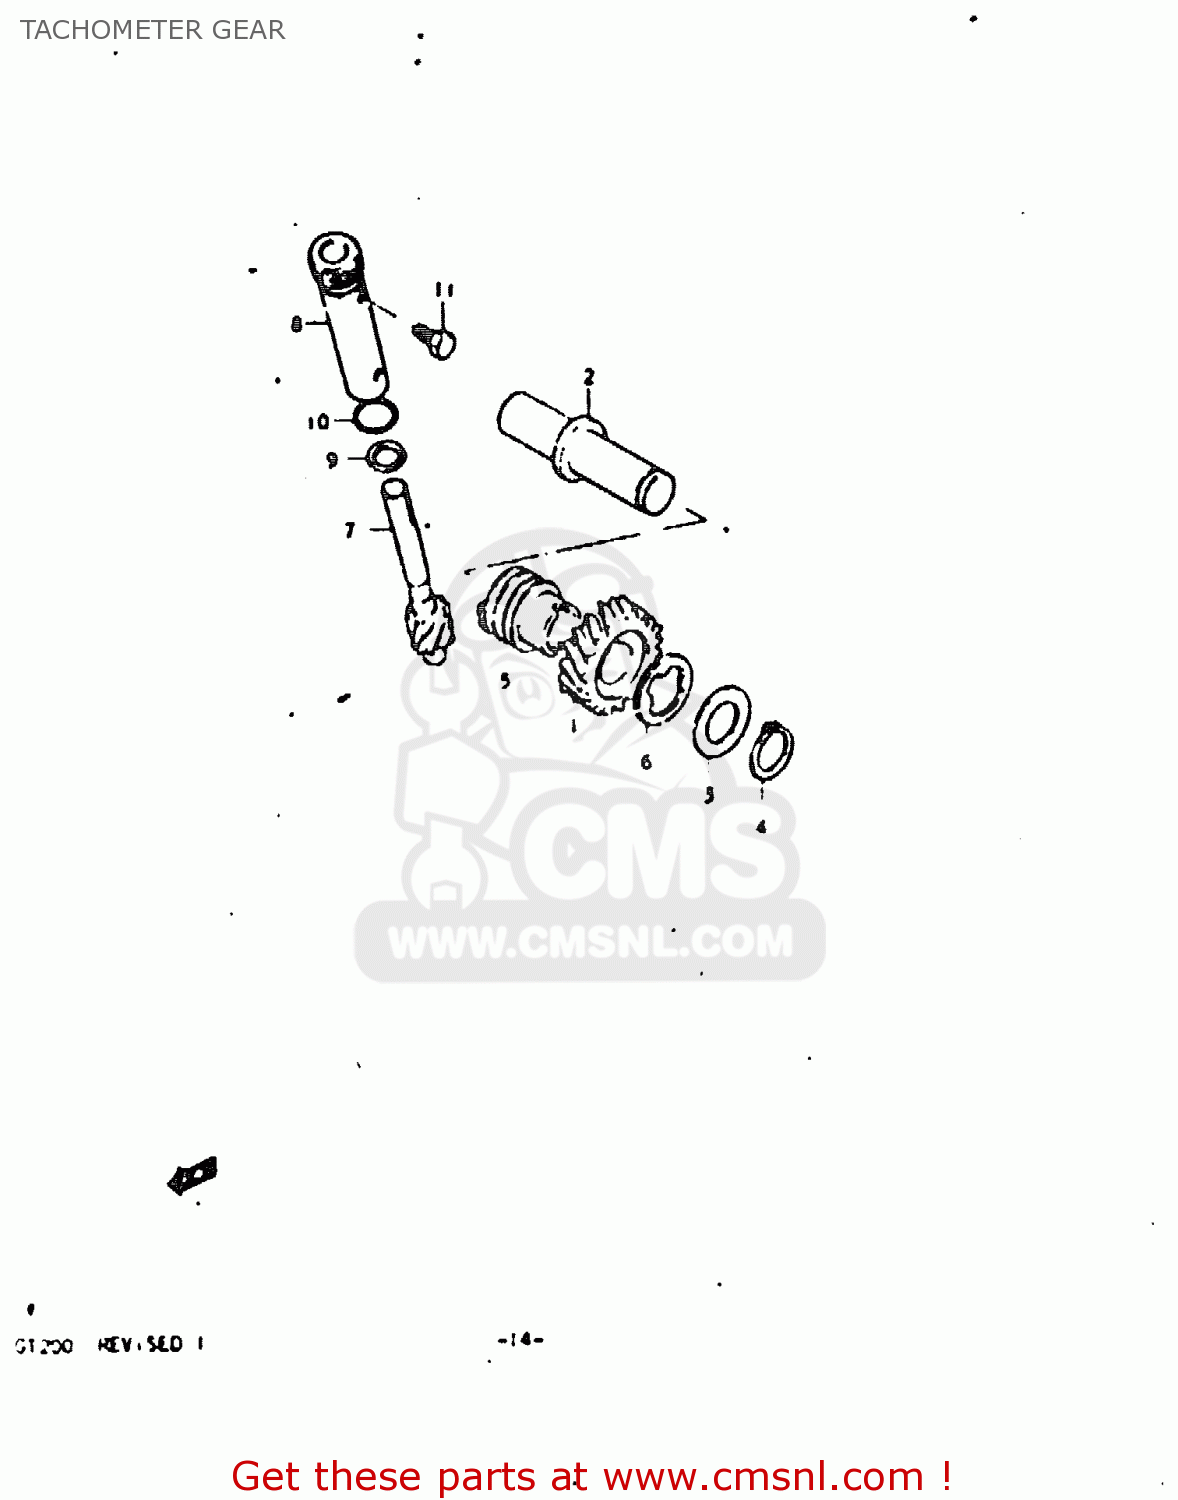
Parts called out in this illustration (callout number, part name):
1	GEAR, TACHOMETER DRIVE NO.2
2	SHAFT,TACHOMETER DRIVEN GEAR
3	WASHER,THRUST
4	CIRCLIP
5	GEAR,TACH DRIVE NO.2(NT:3)
6	RETAINER,TACH DRIVEN GEAR NO1
7	GEAR, TACHOMETER DRIVER
8	SLEEVE,TACHOMETER DRIVE GEAR
9	WASHER(8X13.7X1)
10	O RING(D:1.3,ID:9.6)
11	BOLT
